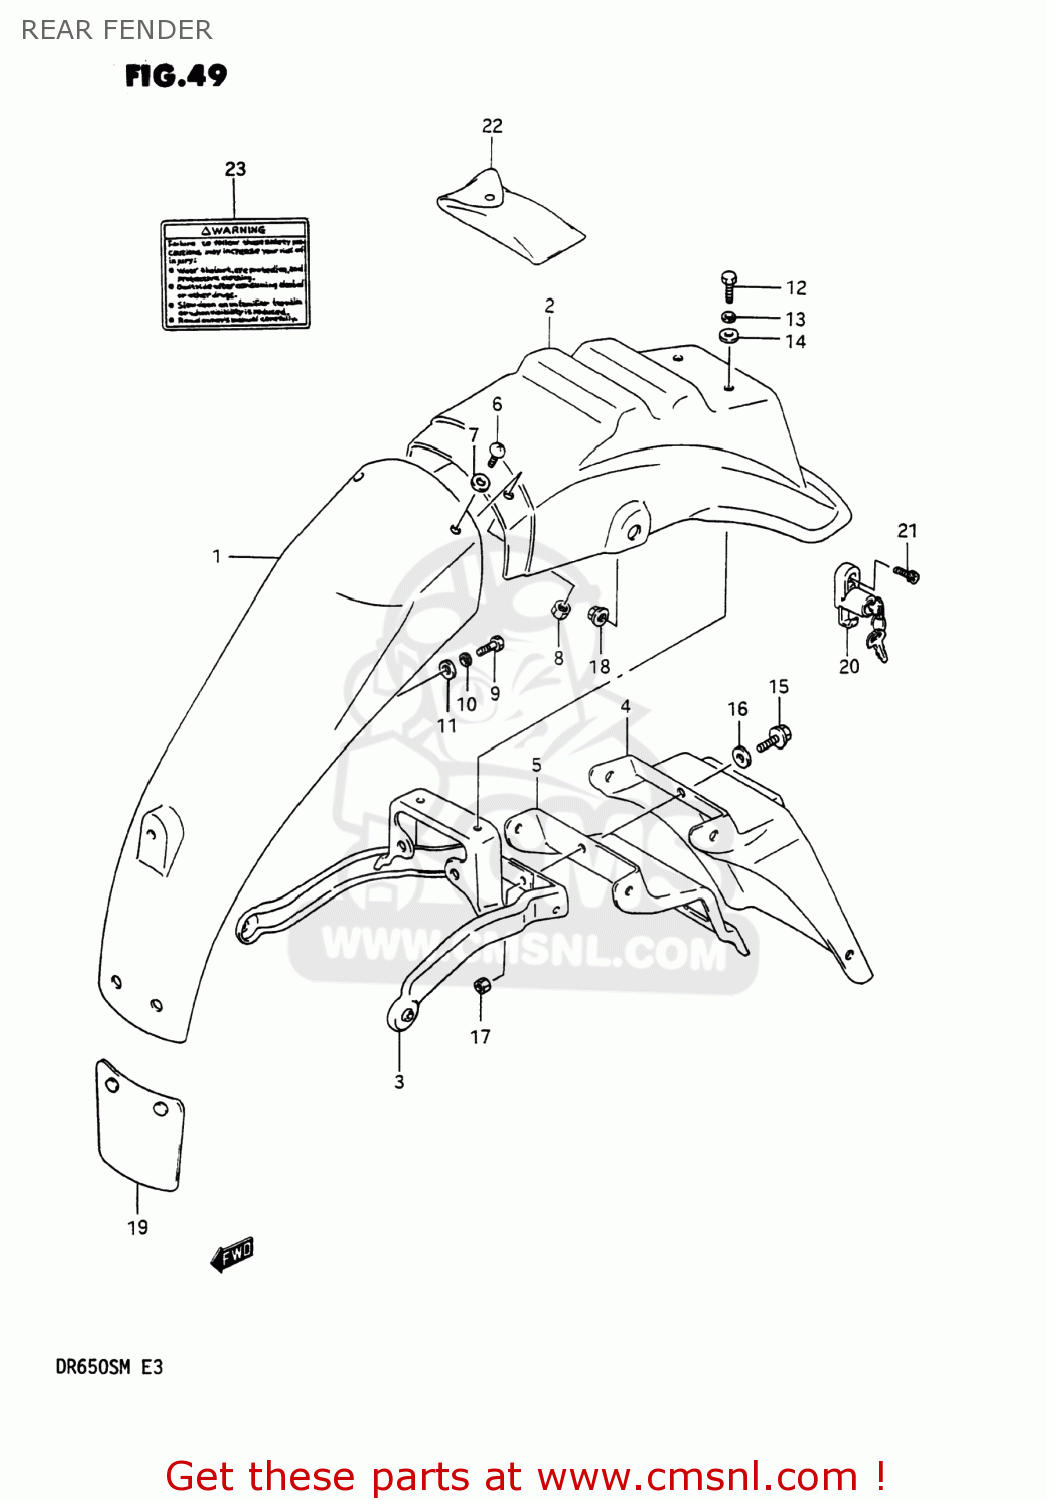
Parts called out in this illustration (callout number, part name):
1	BODY,REAR FENDER,FRONT
2	BODY,REAR FENDER,REAR
3	REINFORCEMENT,REAR FENDER
4	EXTENSION,REAR FENDER
5	REINFORCEMENT,REAR FENDER
6	SCREW, FRONT & REAR
7	WASHER
8	NUT 8MM
9	BOLT 6X16
10	WASHER,LOCK
11	WASHER
12	BOLT
13	WASHER,LOCK
14	WASHER
15	BOLT(6X20)
16	WASHER
17	NUT
18	NUT
19	GUARD,RR FENDER FR MUD
20	LOCK SET,HELMET
21	BOLT
22	TOOL ASSY
23	LABEL
